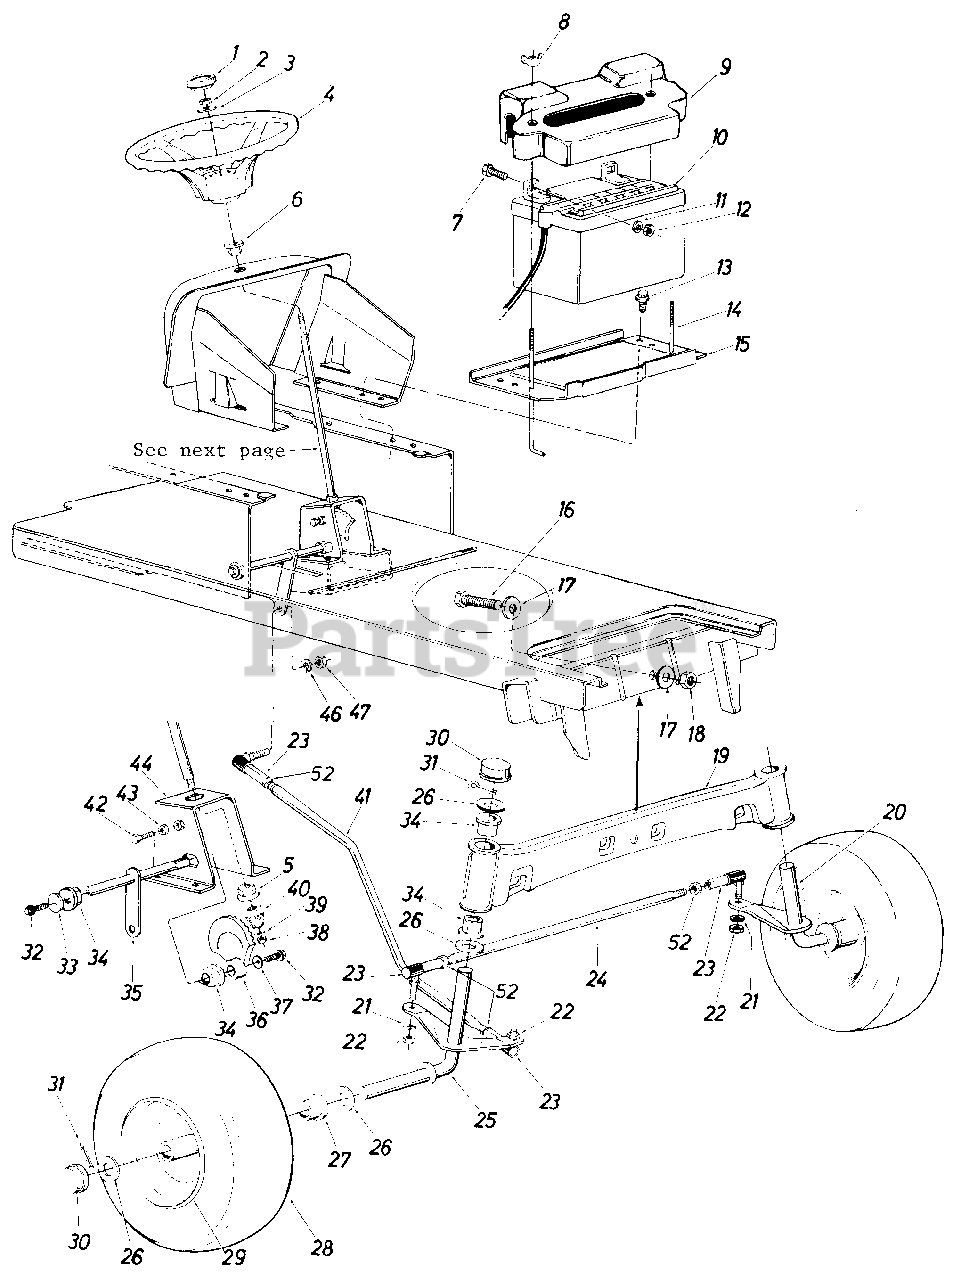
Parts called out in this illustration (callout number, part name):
1	Steering Wheel Cap
2	Hex Cent. L-Nut 5/16-24 Thd.
3	Bell-Wash. 5/16" I.D. x .87" O.D. x .060
4	Steering Wheel
5	Plastic Hex Bearing 5/8" I.D.
6	Steering Column Brg. .890" I.D.
7	Hex Scr. 1/4-20 x .62" Lg.
8	Wing Nut Plastic 1/4-20 Thd.
9	Battery Cover
10	12-V Battery
11	L-Wash. 1/4" I.D.
12	Hex Nut 1/4-20 Thd.
13	Hex Thd. Rolling Scr. 1/4-20 x.50" Lg.
14	Battery Hold Down Rod
15	Battery Plate
16	Hex Scr. 5/8-18 x 2.50" Lg.
17	Flat Wash. .66" I.D. x 2.25" O.D. x .17
18	Hex Cent. L-Nut 5/8-18 Thd.
19	Front Pivot Bar Ass'y.
20	Front Axle Ass'y. L.H.
21	L-Wash. 3/8" Scr.
22	Hex Nut 3/8-24 Thd.
23	Ball Joint Ass'y.
24	Tie Rod
25	Front Axle Ass'y. R.H.
26	Fl-Wash. .780 I.D. x 1.59 O.D.
27	Flange Bearing
28	Front Wheel Ass'y. Comp.
29	Front Wheel Rim Only
30	Dust Cover
31	Cotter Pin 5/32" Dia. x 1.00" Lg.
32	Hex Scr. 3/8-24 x .75" Lg. Grade 5
33	Fl-Wash. 3/8 I.D. x 1.25 O.D. x .090
34	Flange Double "D" Brg. .753 I.D.
35	Steering Arrn Shaft Ass'y.
36	Side Gear Steering
37	Bell-Wash. 3/8" I.D.
38	Hex Cent. L-Nut 5/16-24 Thd.
39	Fl-Wash. 5/16" I.D. x .62 O.D. x .059
40	Pinion Gear Steering
41	Drag Link
42	Hex Nylon Scr. 3/8-16 x 1.25" Lg.
43	Hex Nut 3/8-16 Thd.
44	Steering Gear Sup. Ass'y.
46	L-Wash. 3/8" I.D.
47	Hex Nut 3/8-24 Thd.
52	Hex Jam Nut 3/8-24 Thd.
